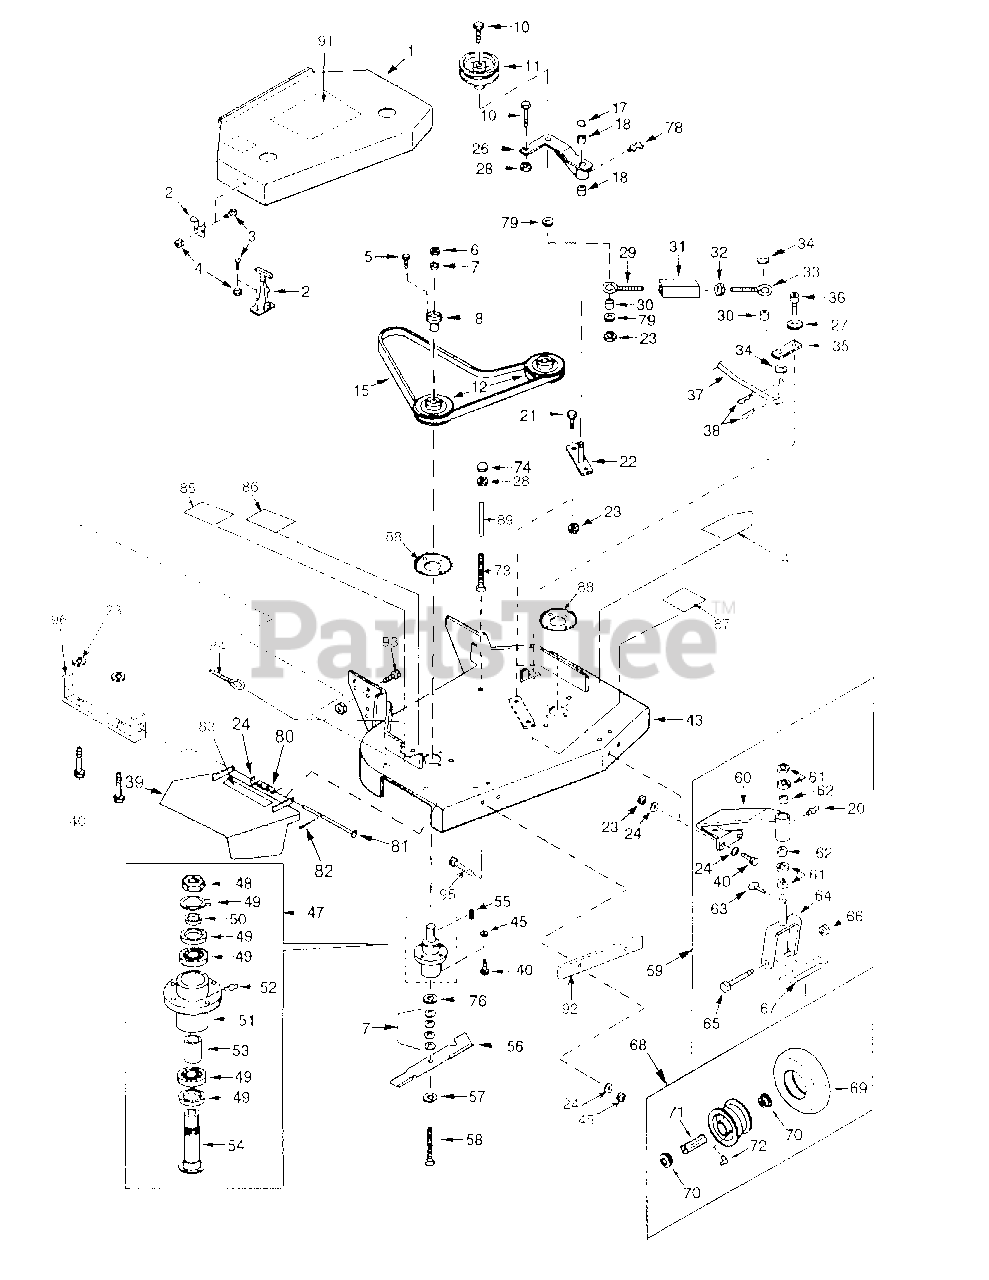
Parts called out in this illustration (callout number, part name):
1	36" Deck Cover
2	Rubber Latch
3	Machine Screw, 10-24 x 1/2 Round Hd.
4	Hex Nut, 10-24 Nylock
5	Cap Screw, 1/4-20 x 3/4 Hex Hd.
6	Hex Nut, 5/8-11
7	Blade Spacer
8	Pulley Bushing
10	Cap Screw, 3/8-16 x 2-1/2 Hex Hd.
11	Idler, Deck Take-up
12	Deck Pulley
15	Drive Belt
17	E-Ring, External
18	Sintered Bushing
20	Grease Fitting, 1/4-28, Taper, Str.
21	Cap Screw, 3/8-16 x 1 Hex Hd.
22	Idler Pivot
23	Hex Nut, 3/8-16 Nylock
24	Flat Washer, 3/8, Small O.D.
26	Pivot Arm, Deck Take-up Idler Pulley
27	Shim Washer, 3/4 x 1/2 x 1/16
28	Hex Nut, 3/8-16
29	Eyebolt, L.H.
30	Sleeve
31	Turnbuckle (36" Deck)
32	Hex Nut, 5/16-18
33	Eyebolt, R.H.
34	Flat Washer, 3/8, Large O.D.
35	Clutch Link
36	Shoulder Bolt, 1/2 X 3/8
37	Rod, Blade Clutch
38	Hairpin, 3/8-7/16
39	Discharge Chute
40	Cap Screw, 3/8-16 x 1-1/4 Hex Hd.
41	Cap Screw, 1/2-13 x 1-1/4 Hex Hd.
42	Lock Washer, 1/2 Heavy
43	36" Cutter Deck
45	Hex Nut, 3/8-16 Stover
46	Belt Guide
47	Spindle Assembly
48	Hex Nut, 1-1/8-12 UNF, Jam
49	Kit, Spindle Repair
50	Seal Spacer
51	Spindle Housing
52	Grease Fitting
53	Internal Spacer
54	Spindle
55	Key, 1/4 x 1/4 x 2
56	Rotary Blade, 16-1/2"
56	Rotary Blade, 18"
57	Flat Washer, 5/8
58	Cap Screw, 5/8-11 x 9-1/2 Hex Hd.
59	Caster Assembly
60	Caster Bracket
61	Caster Spacer
62	Bushing, Caster Bracket
63	Lynch Pin, 7/16 x 1-7/8
64	Caster Yoke
65	Cap Screw, 1/2-13 x 5-1/2 Hex Hd.
66	Hex Nut, 1/2-13 Nylock
67	Sleeve, Caster Wheel Bearing
68	Caster Wheel Assembly
69	Tire, Caster Wheel
70	Bearing Retainer, Caster Wheel
71	Roller Bearing, Caster Wheel
72	Grease Fitting, 1/4-28, 45°
74	Protective Cap
75	Channel, Rubber
76	Flat Washer, 1-1/2 x 5/8 x .055
77	Flat Washer, 3/8, Thick
78	Grease Fitting
79	Flat Washer, 5/16 USS
80	Torsion Spring
81	Deflector Pivot Pin Ass’y
82	Cotter Pin, 1/8 x 1
83	Decal, "Width of Cut"
84	Belt, Rod, Tensioner
85	Decal, Rotating Blade
86	Decal, Warning Safety
87	Decal, Warning Shield
88	Plate, Spindel Backing
89	Spacer, Belt Guard
90	Bracket, Deflector Pivot
91	Label, Command Deck
93	Bolt, Carriage
94	Decal, Danger
95	Bolt, Carriage
96	Bracket Deflector
